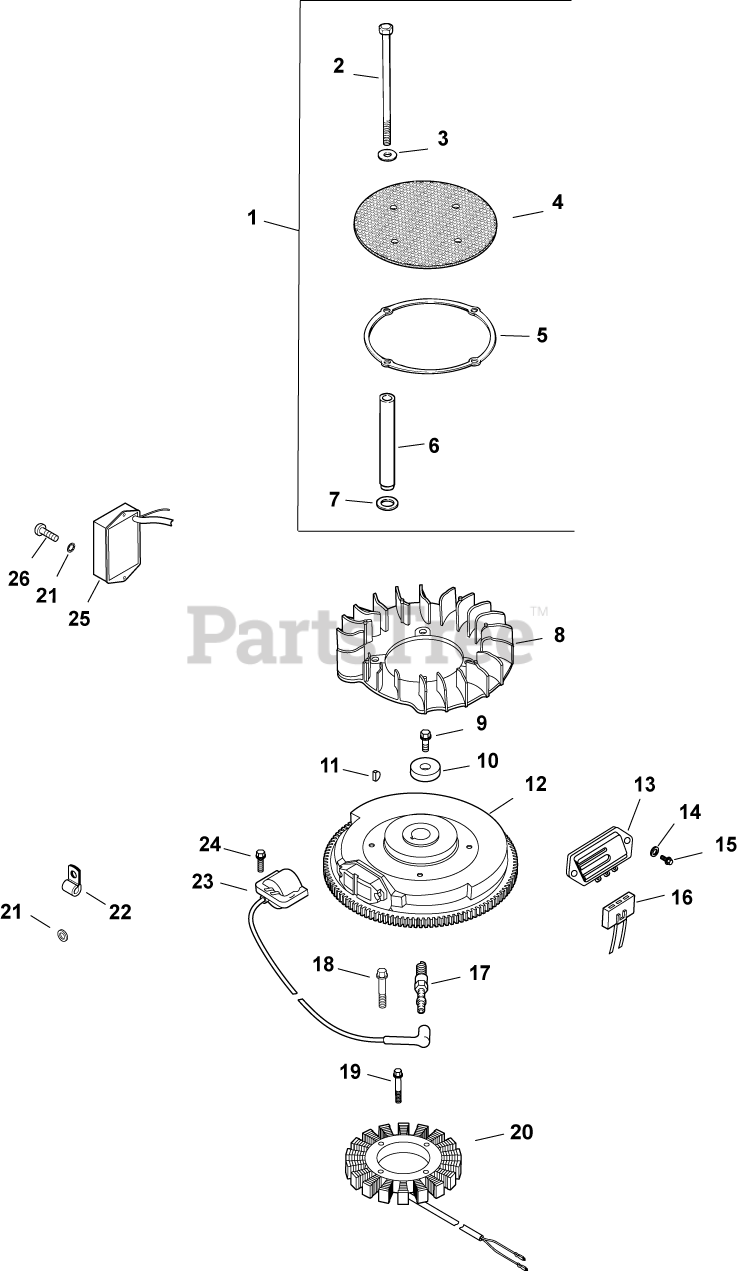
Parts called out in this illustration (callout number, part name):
1	KIT, CHOPPER SCREEN
2	SCREW, CAP M6X1.0X99.5
3	WASHER, FLAT 1/4" (O.D. 5/8")
4	SCREEN, GRASS
5	RING, SUPPORT USE 25 141 08-S
7	WASHER, SPRING 10 MM
9	SCREW, FLG M10X1.5X45 - (#25086361S)
10	WASHER, FLAT 13/32"
11	KEY, 3/16" X 5/8"
12	FLYWHEEL, PAINTED-USE 24 025 56-S
13	REG/RECTIFIER (20/25 AMP)-USE 25 403 20-
14	WASHER, FLAT 3/16"
15	SCREW, PHL HD #11-16X7/8"
16	CONNECTOR, BODY (KM)-USE 25 155 41-S
17	PLUG, SPARK (PRO SERIES)
18	SCREW, M5X0.8X25 - (#25086402S)
19	SCREW, SKT SET #10-24X1/4"
20	KIT, 15 / 20 AMP STATOR
21	WASHER, FLAT 1/4" (O.D. 1/2")
22	CLIP, CABLE
23	MODULE, IGNITION
24	SCREW, FLG THD FRM M5X.8X20-(#25086399S)
25	MODULE, SPEED ADVANCE -USE 24 755 172-S
26	SCREW, THD FRM M4X0.7X10
